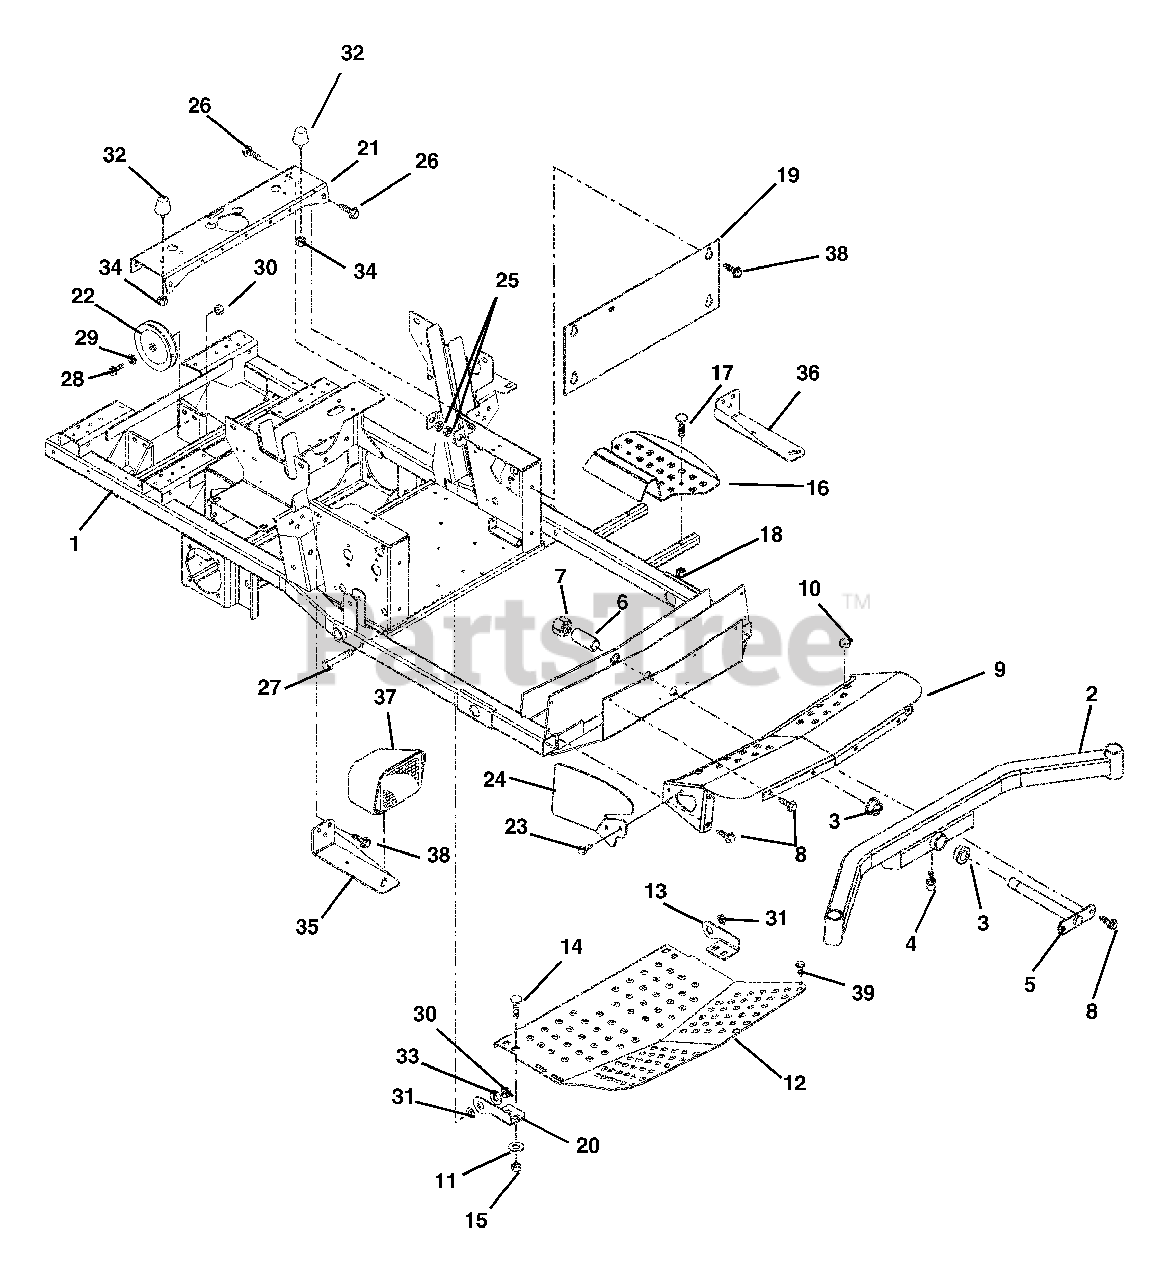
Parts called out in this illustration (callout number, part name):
1	Weldment, Frame
2	Weldment, Front Axle
3	Bushing-Flange 1.020 x 1.385 x .75 x 1.75
4	Fitting-Lube .25-28 x .256
5	Pin-Axle
7	Nut-Locking-Nylon 1.0-14
8	Screw-Tapping .38-16 x .75
9	Weldment, Axle Cover
10	Button, Bumper
11	Washer-Flat-Steel .38 x .875 x .083
12	Panel-Inspection
13	Hinge, Footboard Left Hand
14	Bolt-Round Head Square Neck .38-16 x 1.00 Grade 5
15	Nut-Locking-Nylon .38-16
16	Step-Ingress
17	Bolt-Round Head Square Neck .31-18 x 1.75 Grade 5
18	Nut-Locking-Nylon .31-18
19	Plate-Kick
20	Hinge, Footboard Right Hand
21	Channel-Cross
22	Pulley, Idler
23	Screw-Tapping .25-20 x .50 Hex Washer Head
24	Guard, Foot
25	Nut-Retainer .375-16 x .37
26	Bolt-Serrated Flange Washer Head .38-16 x 1.00
27	Bolt-Hex .50-13 x 3.25 Grade 5
28	Bolt-Hex .50-13 x 2.25 Grade 5
29	Washer-Flat-Steel .505 x .88 x .072
30	Nut-Locking-Nylon .50-13
31	Bushing-Flange .515 x .75 x .275 x 1.12
33	Washer-Flat-Steel .563 x 1.38 x .109
34	Nut-Locking-Flange .312-24
35	Weldment, Light Mount-Right Hand
36	Weldment, Light Mount-Left Hand
37	Headlight
38	Screw-Tapping .38-16 x .50 Hex Washer Head
39	Screw-Tapping .38-16 x 1.00 Hex Washer Head (309)
